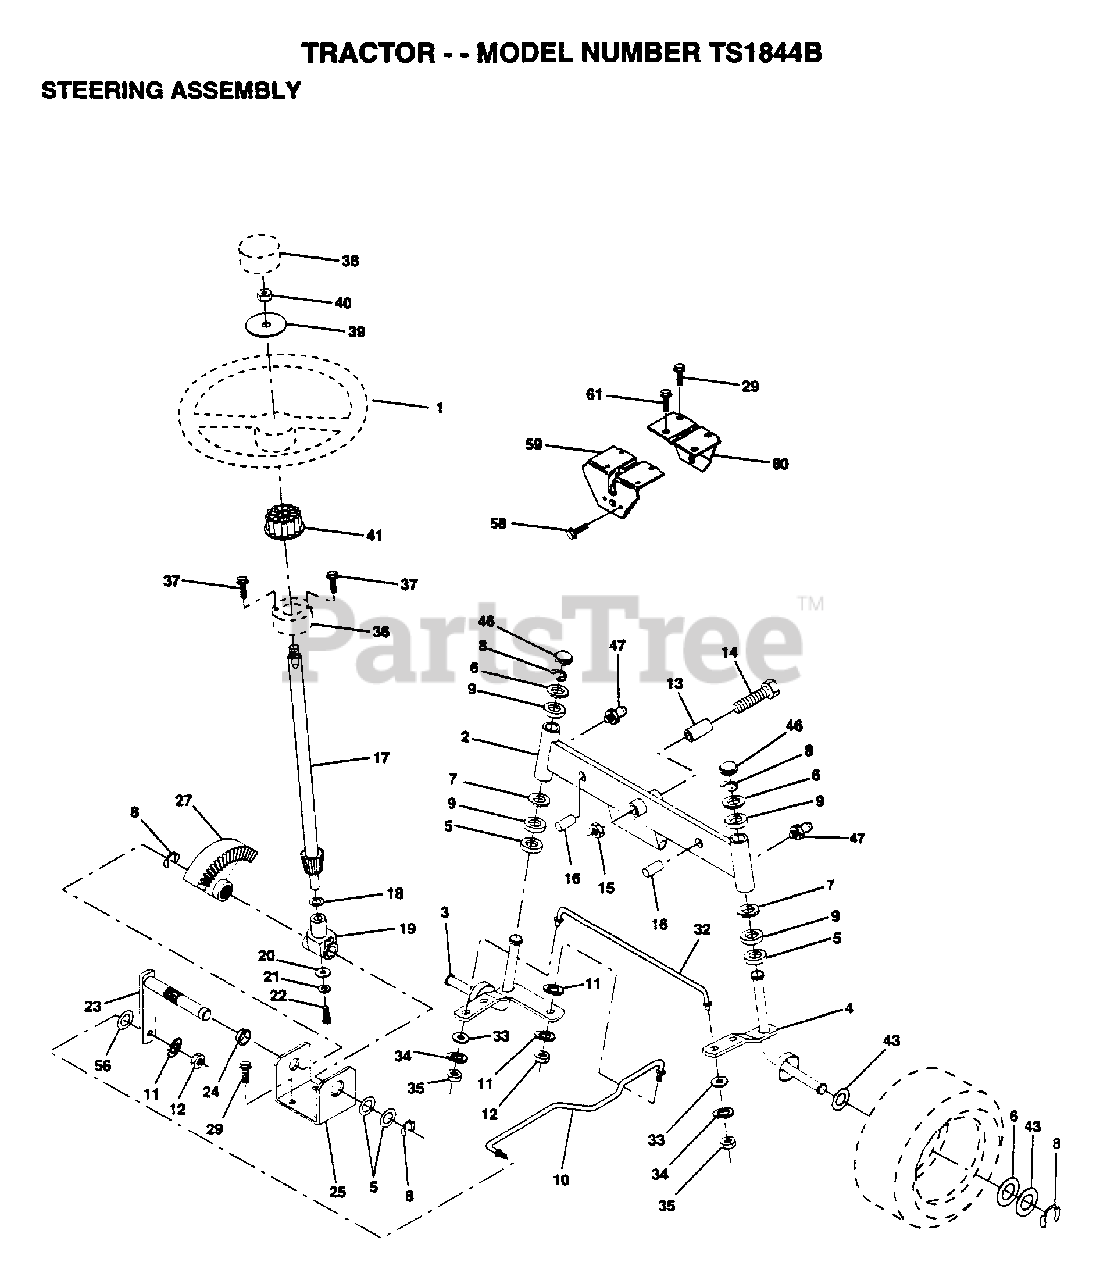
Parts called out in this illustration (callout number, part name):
2	AXLE ASM FRONT
5	WASHER .T
6	WASHER
7	WASHER
8	RING
9	COL. SRTG. BEAR.
11	LOCKWASHER
13	BEARING
14	BOLT LT
15	"NUT-LOC,FLANGE LT"
16	AXLE PIN
18	THRUST WASHER
19	SUPPORT.SHAFT
21	LOCKWASHER
22	"SCREW,SPECIAL"
24	NYLINER T
25	"BRKT,STEERING"
27	GEAR SECTOR
29	SCREW
32	TIE ROD
33	WASHER M
34	LOCKWASHER
35	NUT.LOCK.5/16-24
36	BUSHING.STRG.3/4
37	SCREW.10-24X1/2
38	"INSERT,STR WHEEL"
39	WASHER
41	ADAPTER LT
43	WASHER
46	CAP
47	ZERK M
56	WASHER
58	SCREW LT
59	SUPPORT-SADDL T
60	SUPPORT.SADDLE.FT
61	SCREW SPECIAL
